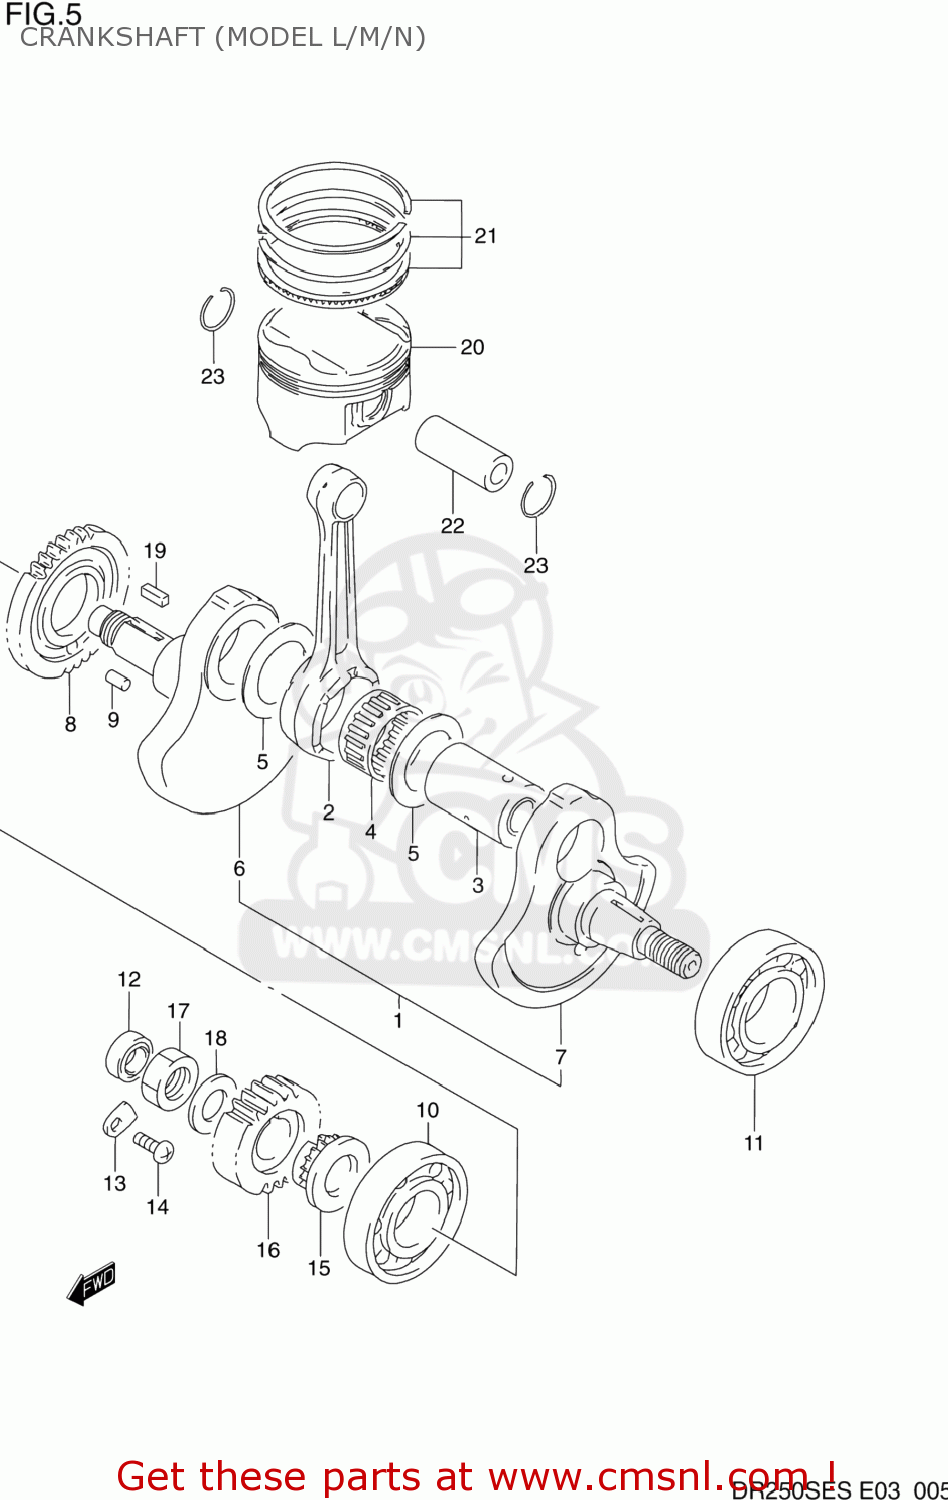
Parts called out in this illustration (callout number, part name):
1	CRANKSHAFT ASSEMBLY
2	CONNECTING ROD
3	PIN COMP,CRANK
4	BEARING(34X43X22)
5	WASHER(34X52X1)
6	CRANKSHAFT,RIGHT
7	CRANKSHAFT,LEFT
8	GEAR,CRANK BAL DRIVE(NT:37)
9	PIN
10	BEARING(30X72X19)
11	BEARING(35X72X17)
12	SEAL,OIL(14X24X6)
13	RETAINER,BEARING
14	SCREW
15	SPROCKET,CAM CHAIN DRIVE
16	GEAR,PRIMARY DRIVE
17	NUT
18	WASHER
19	KEY
20	PISTON
21	RING SET,PISTON
22	PIN,PISTON
23	RING,SNAP
